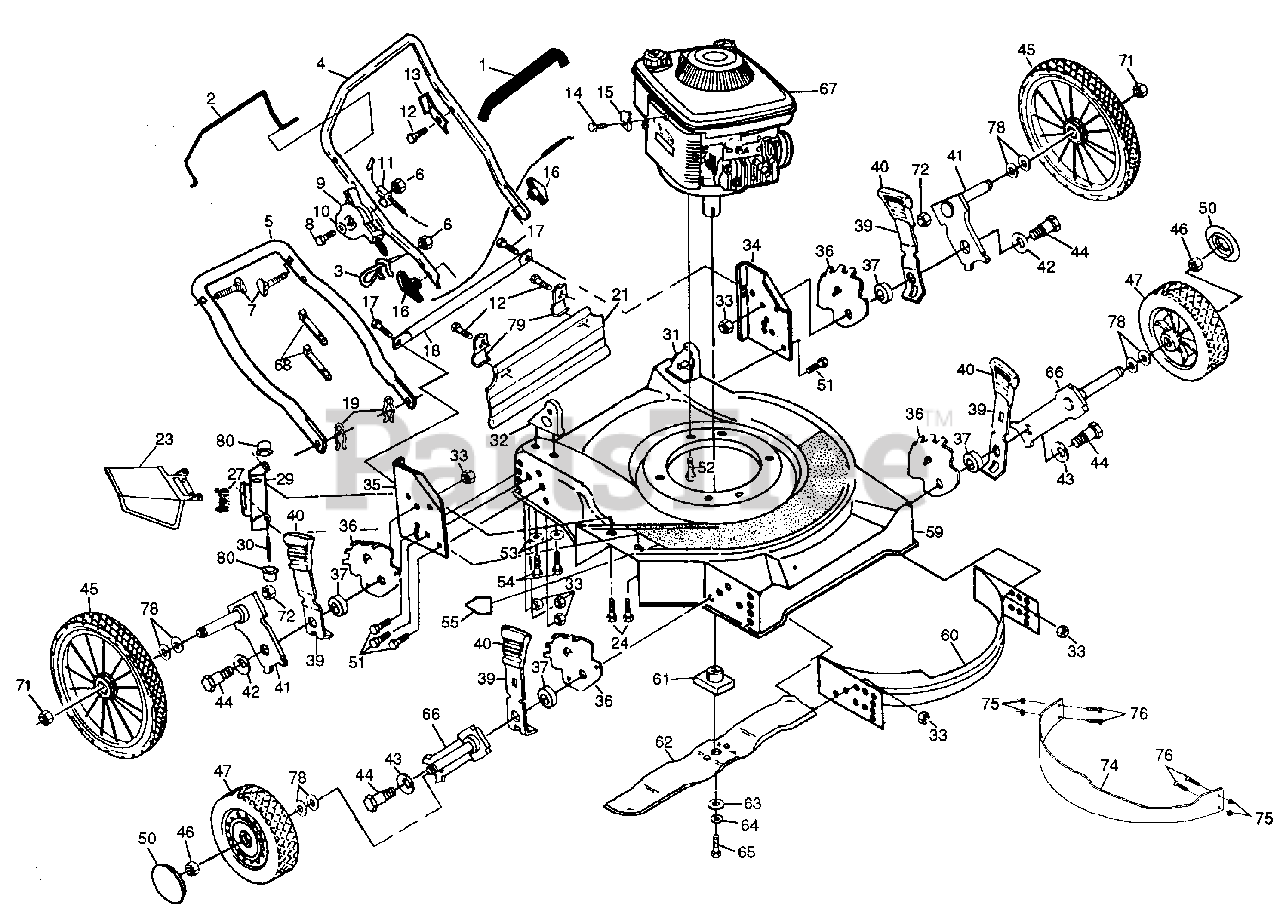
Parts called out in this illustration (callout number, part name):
1	Grip, Handle (AYP part number)
2	Bar, Control
3	Guide, Rope
4	Handle, Upper (AYP part number)
5	Handle, Lower (AYP part number)
6	Locknut (AYP part number)
7	Bolt, Handle 5/16-18 x 1-3/4 (AYP part number)
8	Screw, Machine 1/4-20 x 2-1/8 (AYP part number)
9	Control, Throttle
10	Washer, Flat (AYP part number)
11	Engine, Zone Control Cable
12	Screw, Hex Washer Head 10-24 x 1/2 (AYP part number)
13	Bracket, Up-Stop (AYP part number)
14	Screw, Thread Rolling 10-32 x 5/8 (AYP part number)
15	Clamp, Cable (AYP part number)
16	Knob, Handle (AYP part number)
17	Screw, Hex, Tapping 1/4-20 x 1/2 (AYP part number)
18	Rod, Support (AYP part number)
19	Cotter, Hairpin (AYP part number)
21	Skirt, Rear (AYP part number)
23	Guard, Discharge
24	Screw, Hex Head Thread Rolling 1/4-20 x 3/4 (AYP part number)
27	Spring, Torsion (AYP part number)
29	Bracket, Housing (AYP part number)
30	Rod, Hinge (AYP part number)
31	Bracket Assembly, Handle (Left) (AYP part number)
32	Bracket Assembly, Handle (Right) (AYP part number)
33	Locknut 3/8-16 (AYP part number)
34	Bracket, Wheel, Support (Left) (AYP part number)
35	Bracket, Wheel, Support (Right) (AYP part number)
36	Bracket, Wheel, Adjusting (AYP part number)
37	Spacer (AYP part number)
39	Spring, Selector (AYP part number)
40	Knob, Selector
41	Arm Assembly, Axle (Rear) (AYP part number)
42	Washer, Spring, Rear (AYP part number)
43	Washer, Belleville (AYP part number)
44	Bolt, Shoulder 3/8-16 (AYP part number)
45	Assembly, Wheel and Tire 8.0 x 2.0 (AYP part number)
46	Locknut 3/8-16 (AYP part number)
47	Assembly, Wheel and Tire 14.0 x 2.0
50	Cap, Hub (AYP part number)
51	Bolt, Hex Head 3/8-16 x 3/4 (AYP part number)
52	Screw, Hex Head Thread Rolling (AYP part number)
53	Washer, Flat (AYP part number)
54	Screw, Thread, Cutting 5/16-18 x 3/4 (AYP part number)
55	Decal, Danger (AYP part number)
59	Housing, Lawn Mower
60	Baffle, Front (AYP part number)
61	Adapter, Blade
62	Blade, 22" (AYP part number)
63	Washer, Hardened (AYP part number)
64	Washer, Lock, Helical 3/8 (AYP part number)
65	Screw, Hex, Head 3/8-24 x 1-3/8
66	Arm Assembly, Axle (Front) (AYP part number)
68	Tie, Wire (AYP part number)
71	Locknut (AYP part number)
74	Close Out Plate (AYP part number)
75	Locknut #10-24 (AYP part number)
76	Machine Screw (AYP part number)
78	Spring Washers (AYP part number)
79	Skirt Brackets (AYP part number)
80	Speed Nut (AYP part number)
